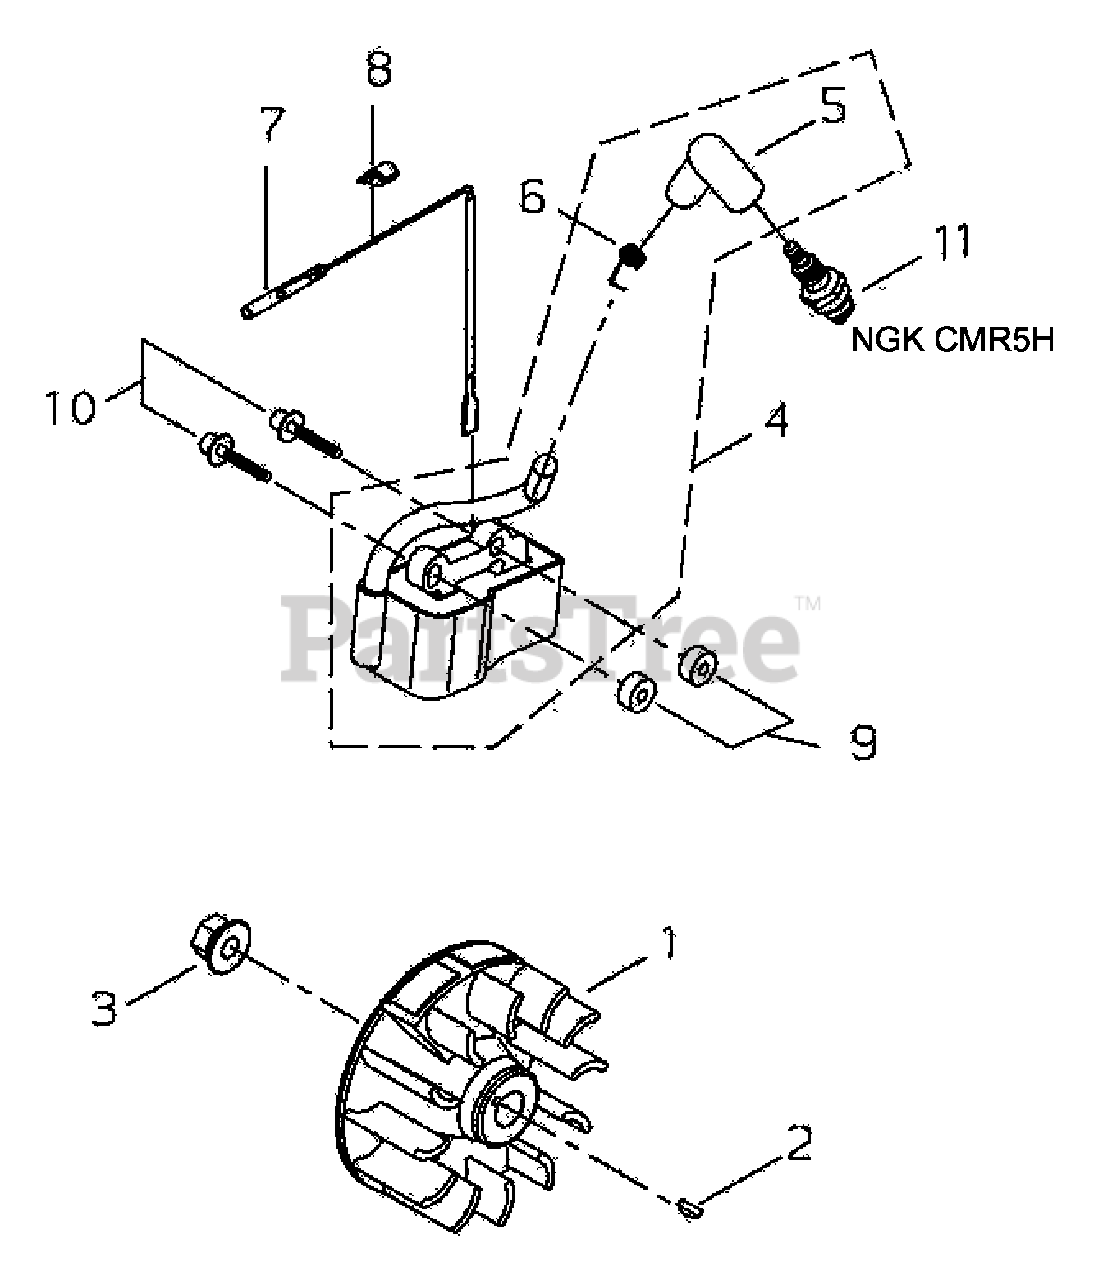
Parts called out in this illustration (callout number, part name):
1	FLYWHEEL
2	KEY, WOODRUFF 3×10
3	NUT M8
4	COIL ASSY, IGNITION
5	COIL ASSY, IGNITION
6	TERMINAL, SPARK PLUG
7	LEAD - IGNITION
8	GROMMET, LEAD
9	INSULATOR 4.2×11×6
10	BOLT M4×26
11	SPARK PLUG - CMR5H
